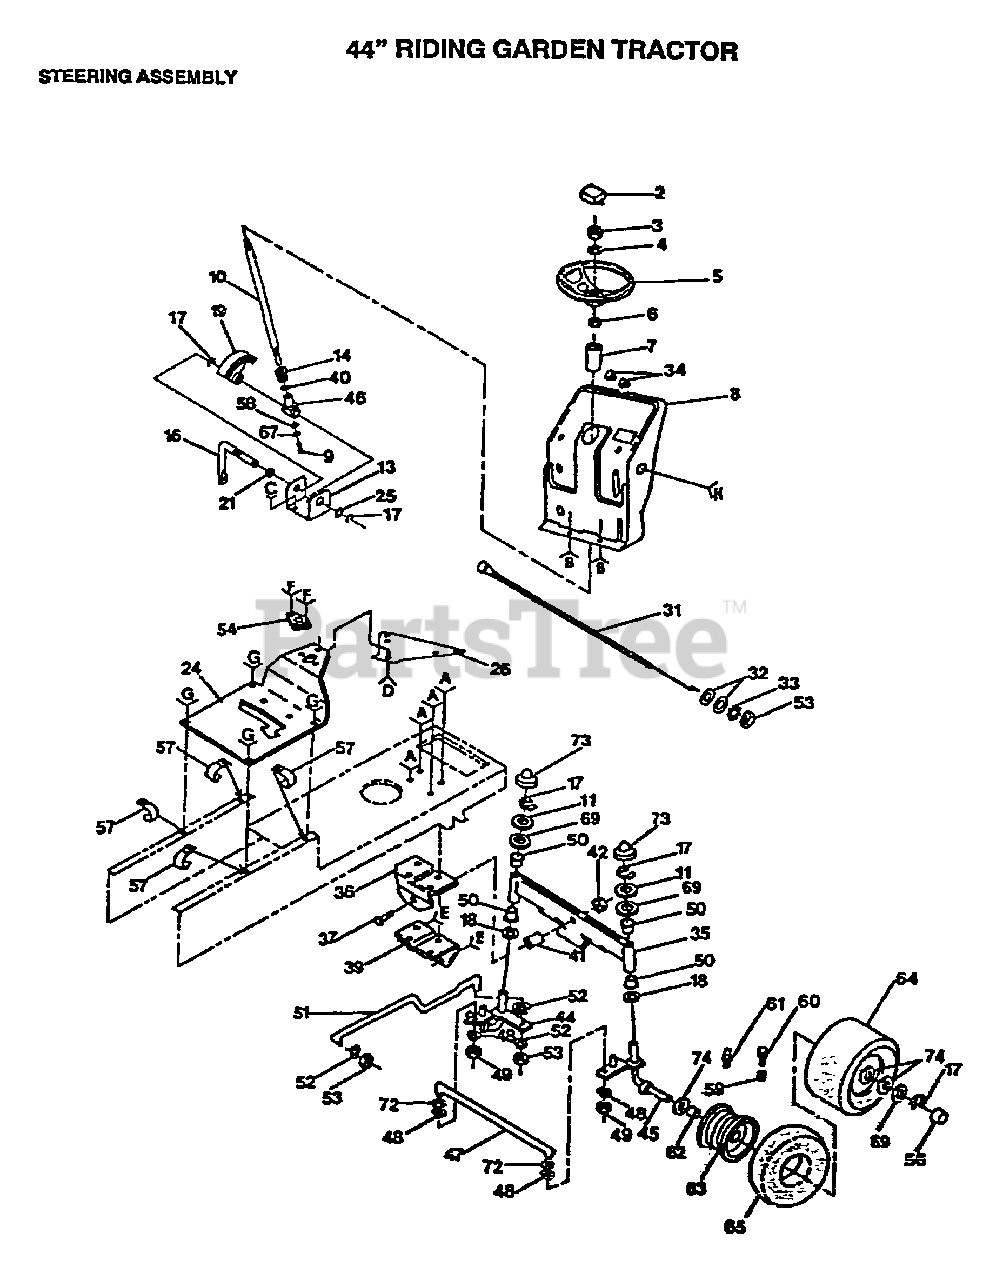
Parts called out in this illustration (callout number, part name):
2	INSERT-WHEEL LT
4	WASHER
6	ADAPTER LT
7	SLEEVE LTV
9	"SCREW,SPECIAL"
11	WASHER
13	"BRKT,STEERING"
14	"GEAR,PINION"
15	SCREW SPECIAL
17	RING
18	WASHER .T
21	NYLINER T
22	SCREW
25	WASHER .T
27	BOLT
32	WASHER
33	LOCKWASHER
34	PLUG-DASH T
35	FRONT AXLE
36	SUPPORT-SADDL T
37	BOLT LT
38	SCREW LT
39	SUPPORT.SADDLE.FT
40	THRUST WASHER
41	BEARING
42	"NUT-LOC,FLANGE LT"
43	SCREW LT
44	SPINDLE-LH LT
46	SUPPORT.SHAFT
48	LOCKWASHER
49	NUT.LOCK.5/16-24
50	COL. SRTG. BEAR.
52	LOCKWASHER
56	HUB CAP
57	CLIP T
59	VALVE CAP
60	VALVE STEM LT
61	FITTING LT
62	"FLANGE, BEARING"
65	TUBE.5.3/4.5/6
66	BOLT
67	LOCKWASHER
68	NUT
69	WASHER
70	SCREW
72	WASHER M
73	CAP
74	WASHER
